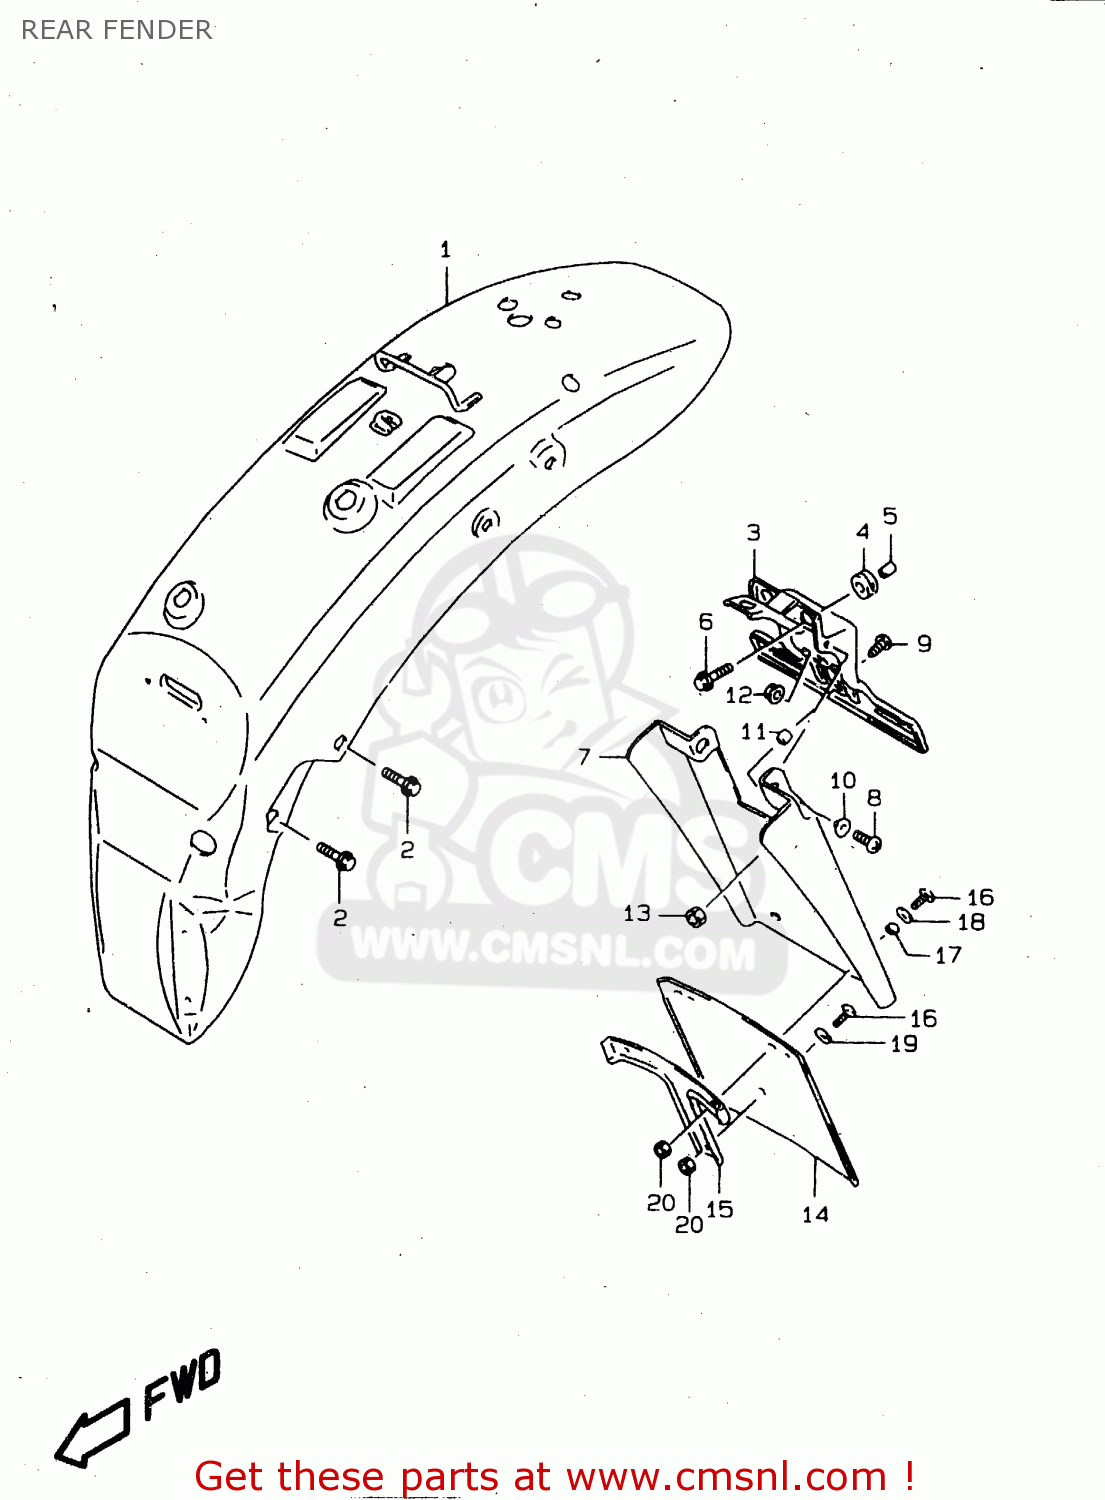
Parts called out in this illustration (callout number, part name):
1	FENDER,RR
2	BOLT
3	BRACKET,LICENSE LAMP
4	CUSHION
5	SPACER
6	BOLT(6X20)
7	EXTENSION,RR FENDER
8	SCREW
9	SCREW 6X16
10	WASHER
11	SPACER(6.2X8.3X6.1)
12	NUT
13	NUT
14	MUD FLAP, REAR FENDER
15	PLATE, MUD FLAP
16	SCREW 5X12
17	SPACER(5.5X8X4)
18	WASHER
19	WASHER(5.5X16X1.2)
20	NUT
